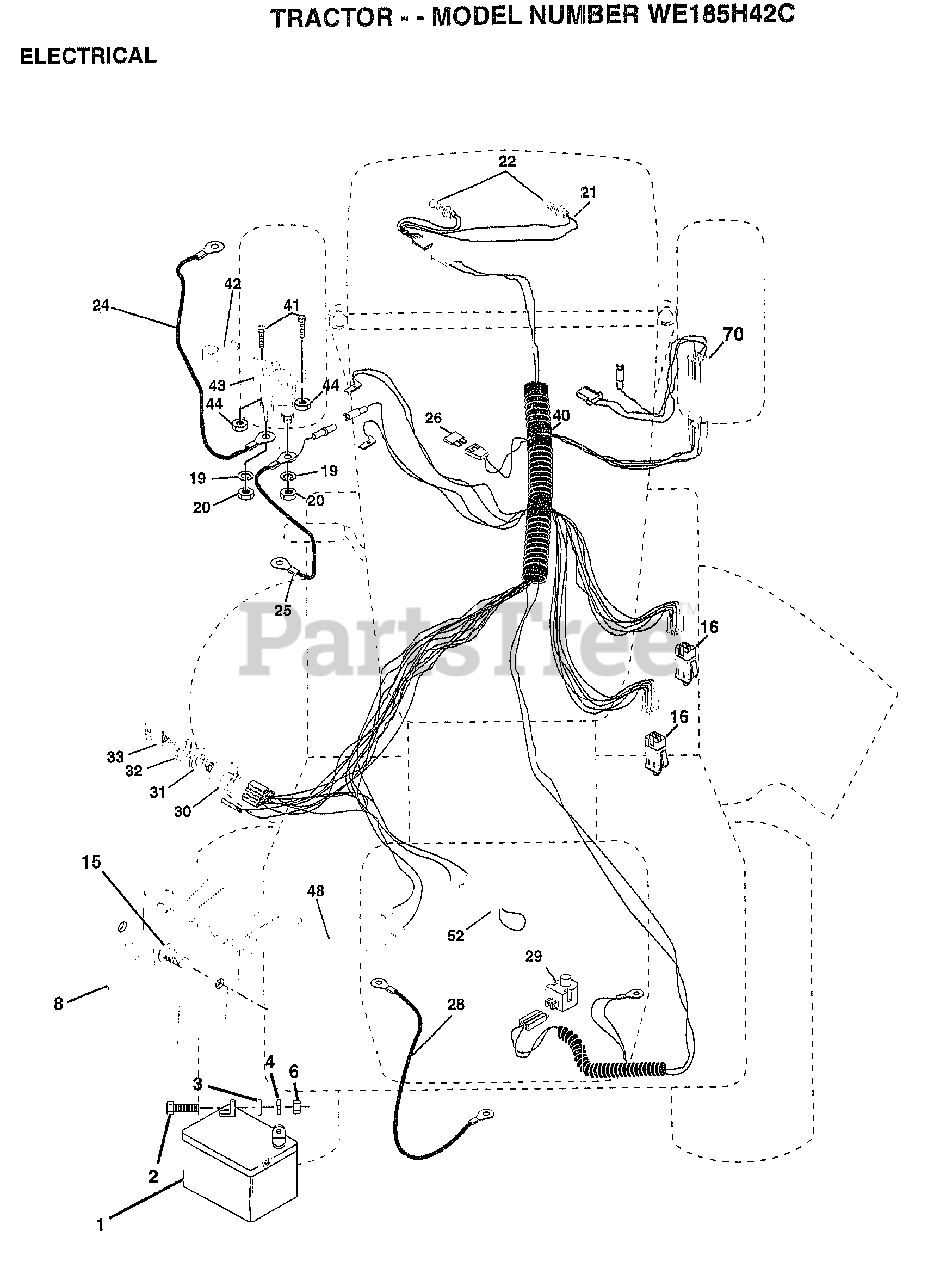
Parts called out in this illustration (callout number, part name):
2	BOLT LT
3	WASHER
4	LOCKWASHER
8	"CASE,BATTERY.MECH"
15	FASTNER.SNAP-IN
16	SWITCH INTERLOCK
20	NUT
21	"HARNESS,LIGHT SOC"
22	HEADLAMP BULB
24	"CABLE T, BATTERY"
25	CABLE.BTRY.6GA.RD
26	FUSE HYT
28	CABLE T
29	SWITCH SEAT
30	SWITCH IGN 4POS
31	NUT IGNITION
32	COVER KEY SWITCH
33	KEY
40	HARNESS-IGNITION
41	BOLT HXHD FIN
44	NUT HXKEP 1/4X20
48	ADAPTER AMMETER
52	PROTECTION LOOP
70	HARNESS ENG DUAL
